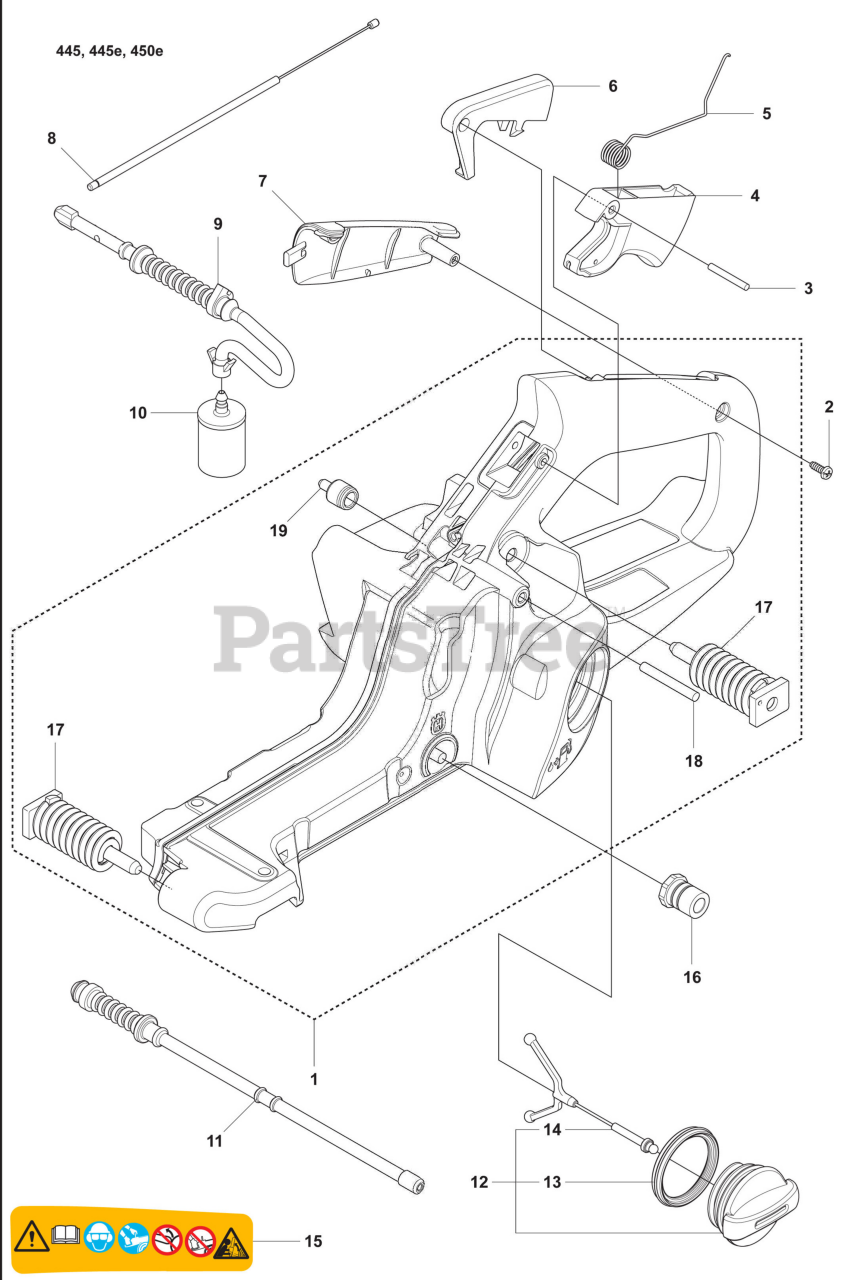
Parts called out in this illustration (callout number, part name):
1	Fuel Tank Assembly
4	Throttle Trigger
6	Throttle Lockout
7	Handle Insert
8	Throttle Cable Assembly
9	Fuel Hose, RP
10	Fuel Filter Kit
11	Return Hose
12	Fuel Tank Cap Assembly, Grey
13	Sealing Gasket
16	Lateral Support
17	Anti-Vibration Element
18	Grooved Pin
19	Tank Vent Assembly
